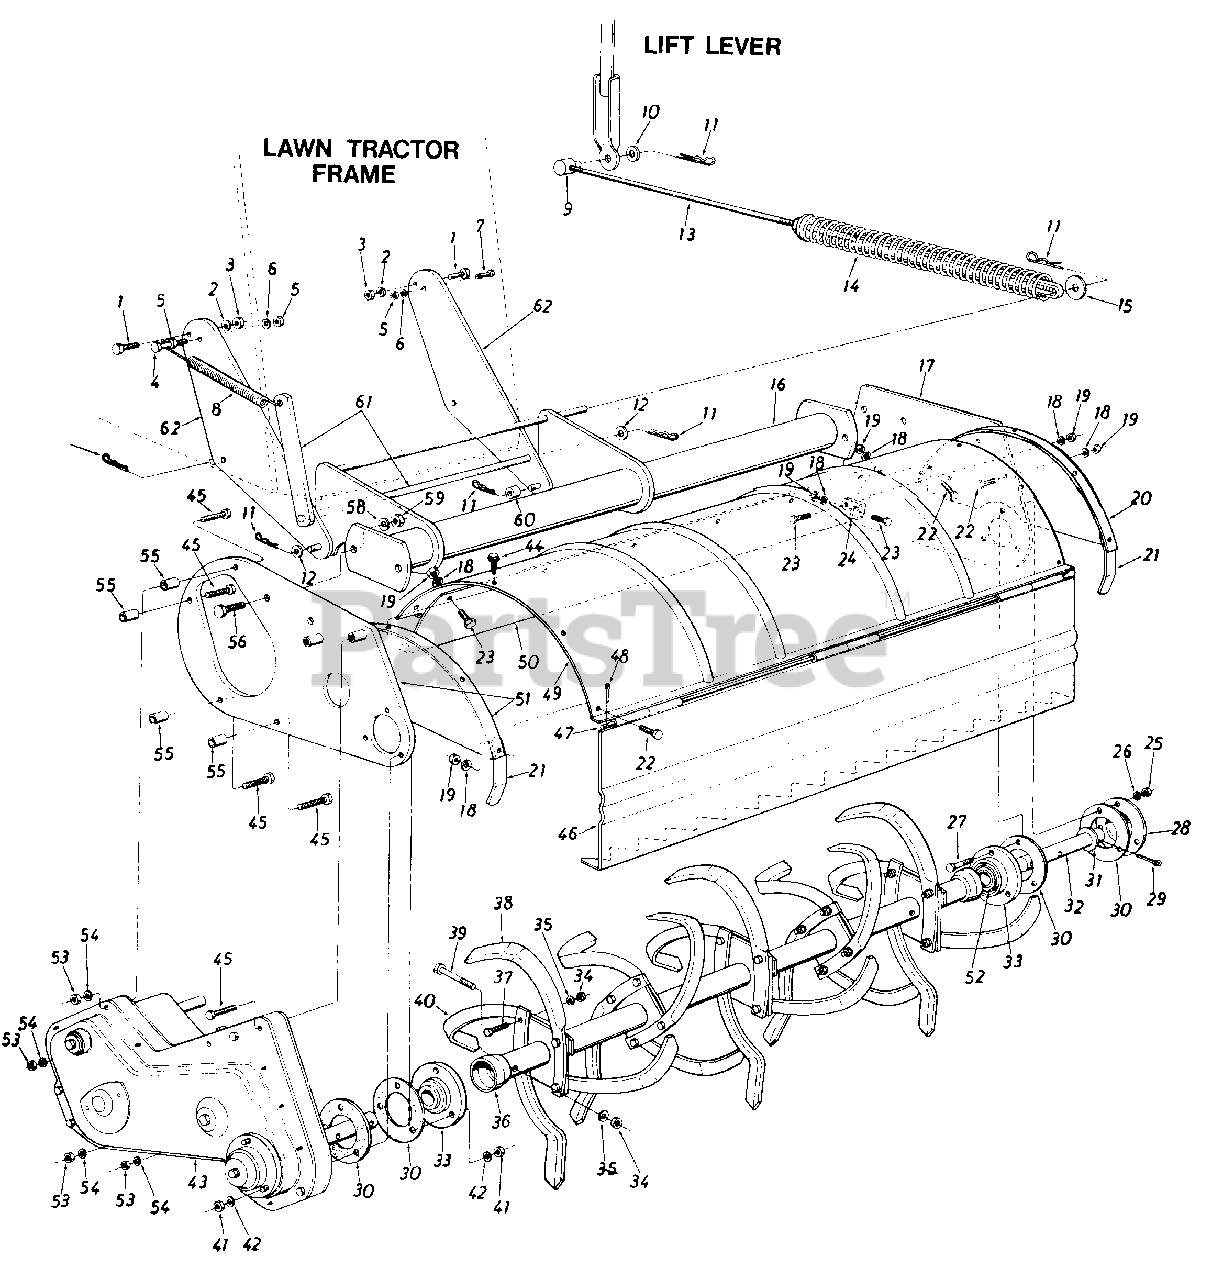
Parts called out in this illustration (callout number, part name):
1	Hex Bolt 3/8-24 x .88" Lg.*
2	L-Wash. 3/8" I.D. Heavy Duty
3	Hex Nut 3/8-2 Thd.*
5	Hex Nut 5/16-24 Thd.*
6	L.-Wash. 5/16" I.D.*
7	Hex Bolt 5/16-24 x 1.00" Lg.*
8	Extension Spring .56" O.D. x 7.75" Lg.
9	Adjustment Ferrule 1/2-13 Thd.
10	FI.-Wash. .640" I.D. x 1.24" O.D. x.060
11	Intern. Cotter Pin 1/2" Dia.
12	Fl.-Wash. .510" I.D. x 1.0" O.D. x .060
13	Lift Rod Ass'y. 39.0" Lg.
14	Compression Spring 1.50" O.D. x 15.0" Lg.
15	Fl.-Wash. .51" I.D. x 1.50" O.D. x.075
16	Pivot Bracket Assembly
19	Hex Nut 5/16-24 Thd.*
23	Hex Bolt 5/16-24 x .62" Lg.*
24	Chute Pivot Bracket
25	Hex Cent. L-Nut 5/16-18 Thd.
26	L.-Wash. 5/16" I.D.*
27	Hex Bolt 5/16-18 x 1.0" Lg. (Grade 5)
30	Gasket for Brg. Housing
31	Fl.-Wash. 1.25" I.D. x 2.00" O.D. x .06
32	Tine Shaft R.D. 1.25" Dia. x 6.25" Lg.
33	Bearing Housing w/Bearing
34	Hex Nut 3/8-2 Thd.*
35	L.-Wash. 3/8" I.D. Heavy Duty
41	Hex Cent. L.-Nut 5/16-18 Thd.
42	L.-Wash.5/16" I.D.*
43	Chain Case Ass'y. Comp.
44	Hex Wash. TT Tap. Scr. 5/16-18 x .62" Lg.
45	Hex Bolt 1/4-20 x 2.75" Lg.*
48	Cotter Pin 1/8" Dia. x 1.00" Lg.*
53	Hex Nut 1/4-2 Thd.*
54	L.-Wash. 1/4" I.D.*
55	Spacer.28" I.D. x .62" O.D. x .90" Lg.
56	Hex Bolt 1/2-13 x 1.00" Lg.*
58	L.-Wash. 1/2" I.D.*
59	Hex Nut 1/2-13 Thd.*
60	Spacer. 50" I.D. x 1.00" O.D. x.50" Lg.
61	Idler Bracket Support Arm Ass'y.
62	Pivot Bracket Support
